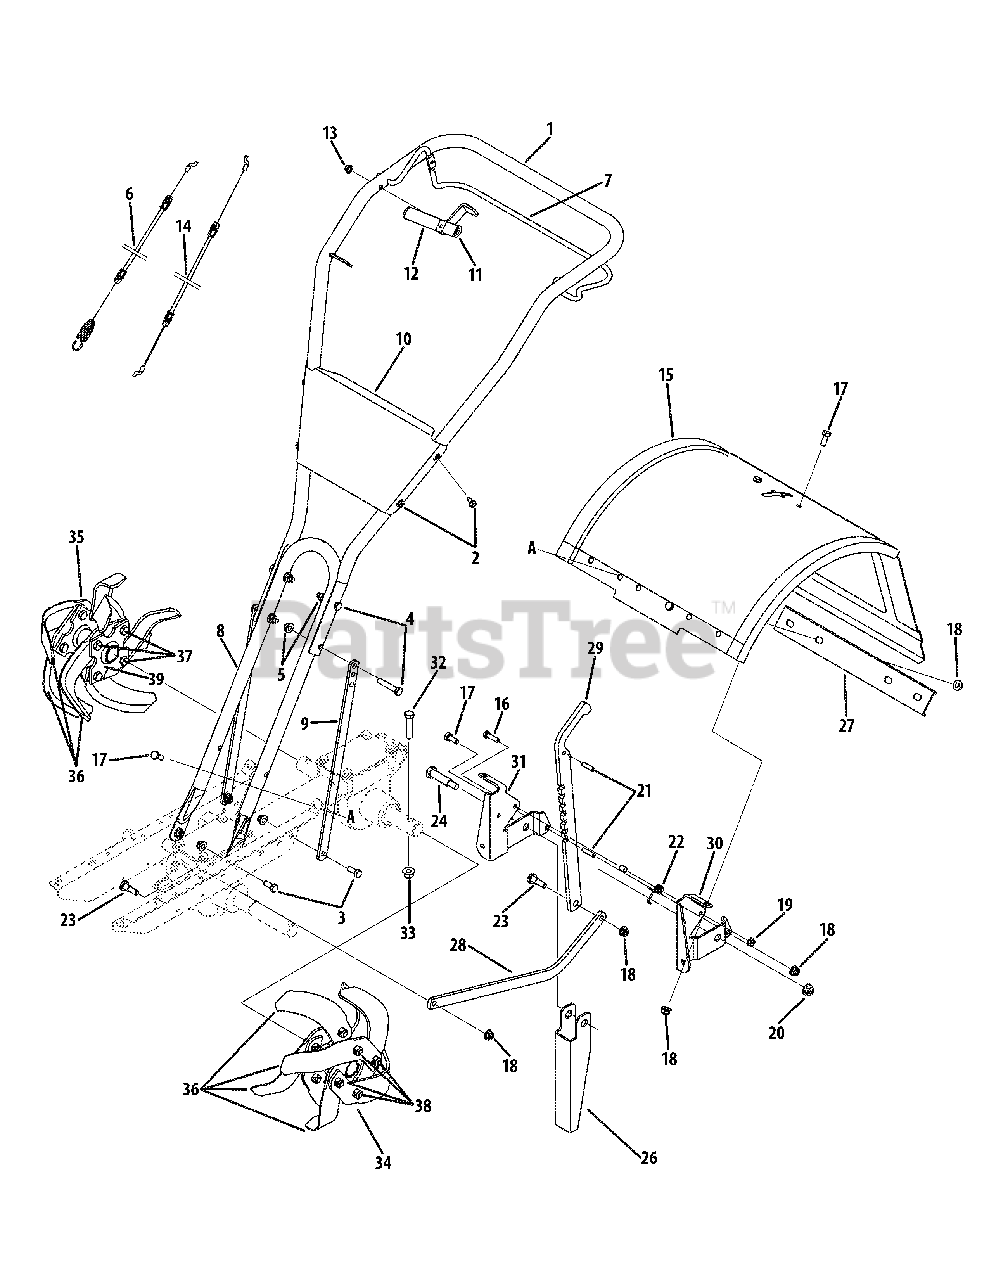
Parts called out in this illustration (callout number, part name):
3	Hex Screw, 5/16-18 x .75
4	Hex Screw, 5/16-18 x 1.75
5	Flange Lock Nut, 5/16-18
6	Forward Cable
13	Speed Nut, .3125
14	Reverse Cable
16	Hex Screw, 1/4-20 x 1.00
17	Hex Screw, 5/16-18 x .75
18	Flange Lock Nut, 5/16-18
19	Flange Lock Nut, 1/4-20
20	Flange Lock Nut, 3/8 -16
21	Spring Pin, 1/4 x 1.00
22	Torsion Spring
23	Shoulder Screw, 5/16-18 x .405 x .435
24	Shoulder Screw, .498 x 1.635
25	Split Spacer, .350 x .268 x .375
32	Hex Screw, 3/8-16 x 1.75
33	Flange Lock Nut, 3/8 -16
34	Tine Assembly, Left 10 x 14
34	Tine Assembly, Left 10 x 16
35	Tine Assembly, Right 10 x 14
35	Tine Assembly, Right 10 x 16
37	Hex Screw, 3/8 -16 x 1
38	Hex Lock Nut, 3/8 -16
